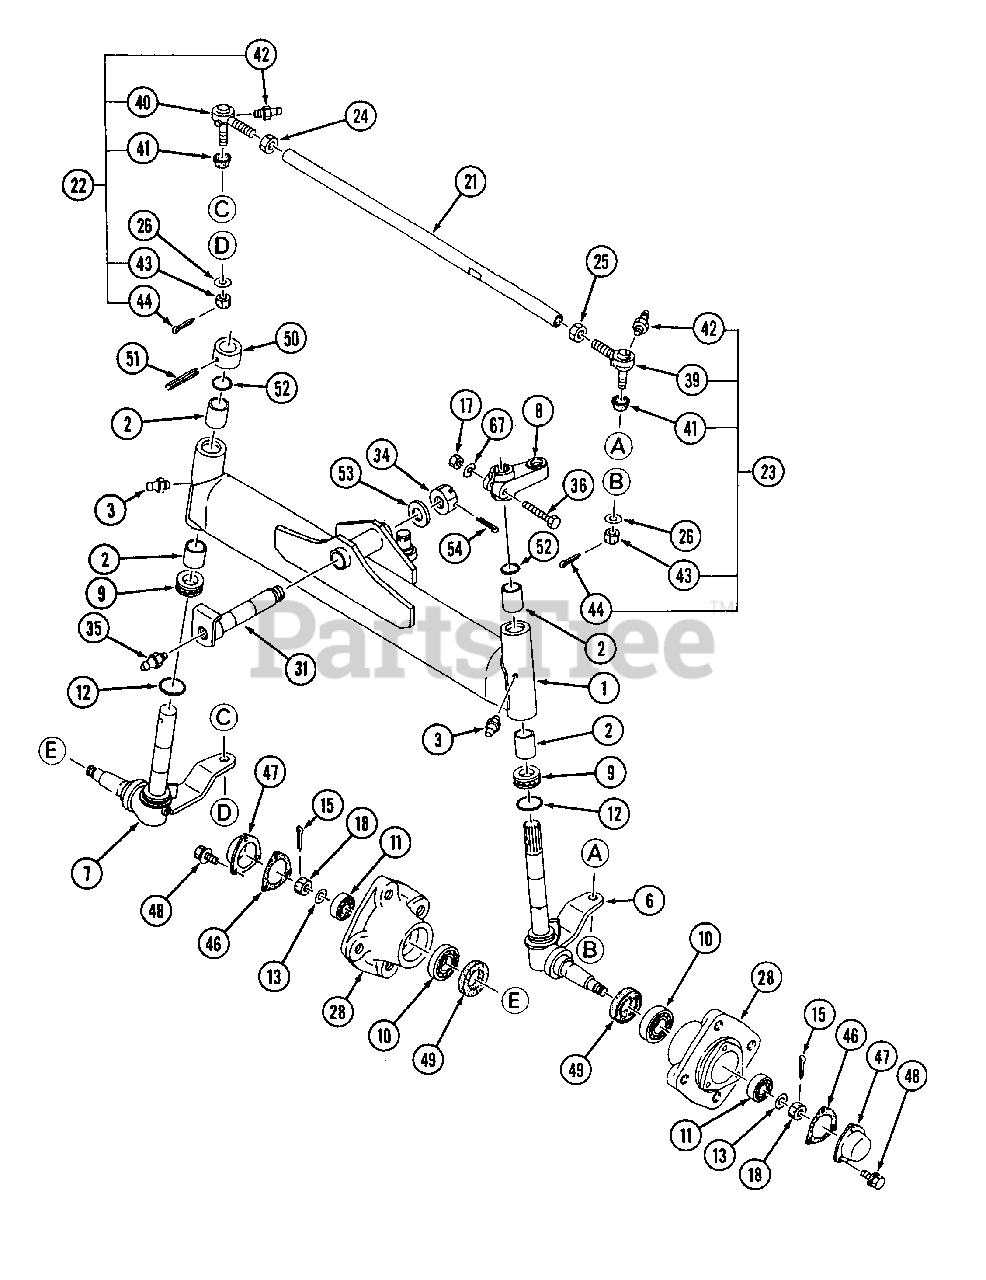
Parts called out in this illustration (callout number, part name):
3	Nipple, Grease
13	Washer
22	End Ass'y. - Tie Rod R.H. Side (L.H. Thread)
23	End Ass'y. - Tie Rod L.H. Side (R.H. Thread)
24	Nut (L.H. Thread) M17
25	Nut (R.H. Thread) M17
28	Hub, Front Wheel
35	Nipple, Grease
41	Cover, Dust
42	Nipple, Grease
43	Nut
44	Pin, Split
